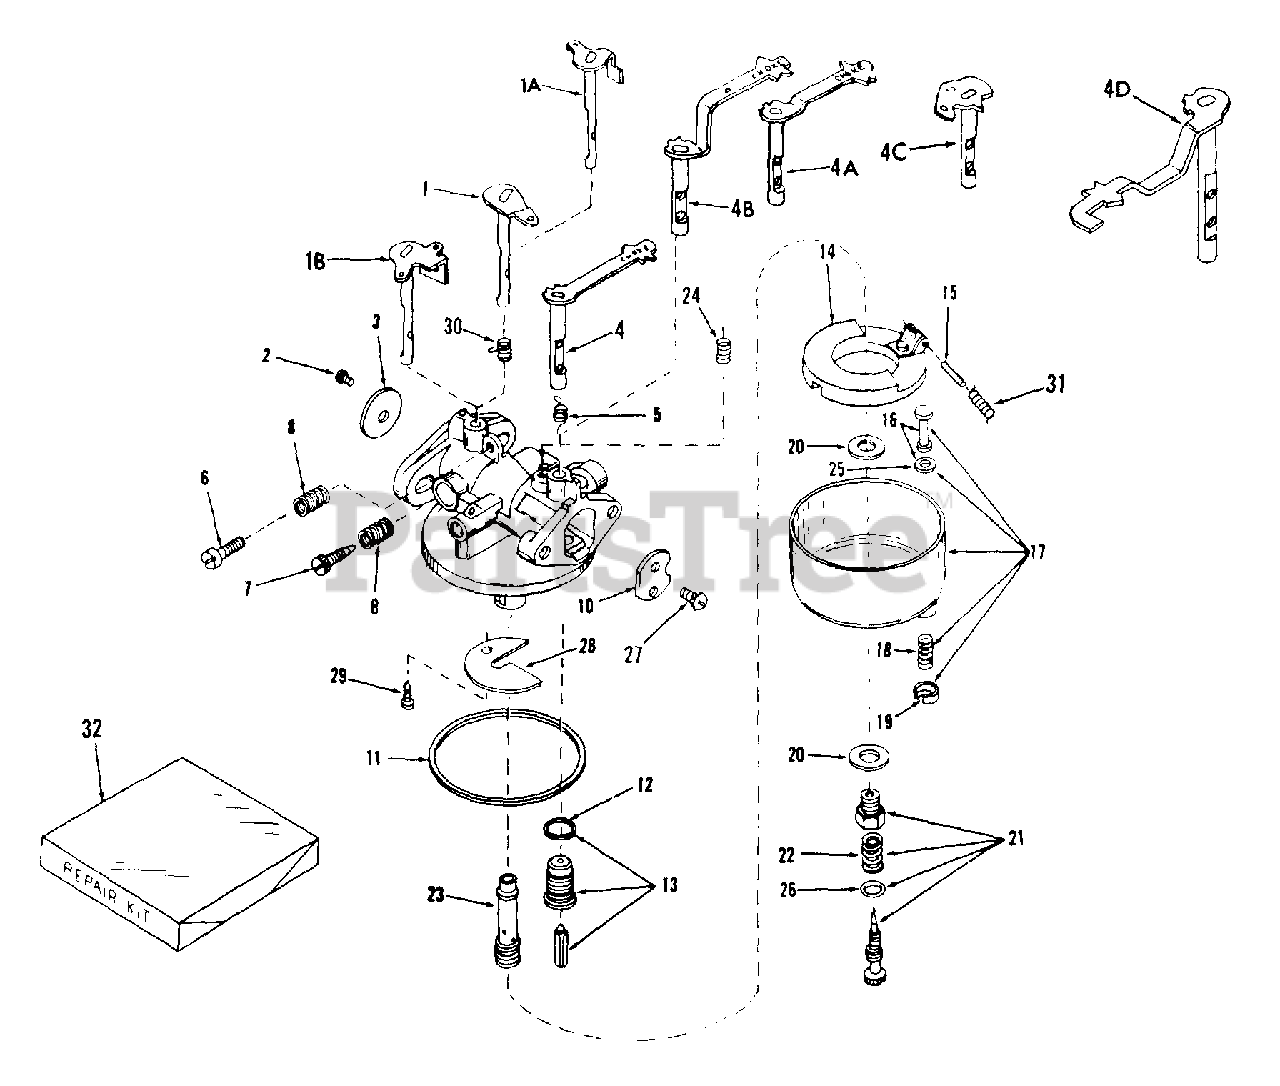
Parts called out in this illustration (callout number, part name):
1A	"Shaft & Lever Assy., Throttle
2	Screw, Sems, 6-32 x 3/16
3	Shutter, Throttle
4	Shaft & Lever Assy., Choke
6	Screw, Throttle adjusting
7	Needle, Idle adjusting
8	Spring, Adjusting needle
10	Shutter, Choke
11	Gasket, Bowl-to-body
12	Gasket, Valve seat
13	Valve, Seat & Gasket Assembly
15	Shaft, Float
16	Stem Assembly, Bowl drain
17	Fuel Bowl & Drain Assembly
18	Spring, Bowl drain
19	Retainer, Bowl drain stem
20	Gasket, Bowl-to-body
21	Needle Assembly, Power adjusting
22	Spring, Power needle
23	Nozzle, Main
24	Spring, Choke stop
25	Gasket, Drain stem
26	"Oll Ring
27	Screw, Sems
28	Baffle, Carburetor
29	Screw, Baffle
31	Spring, Float shaft
32	Repair Kit
